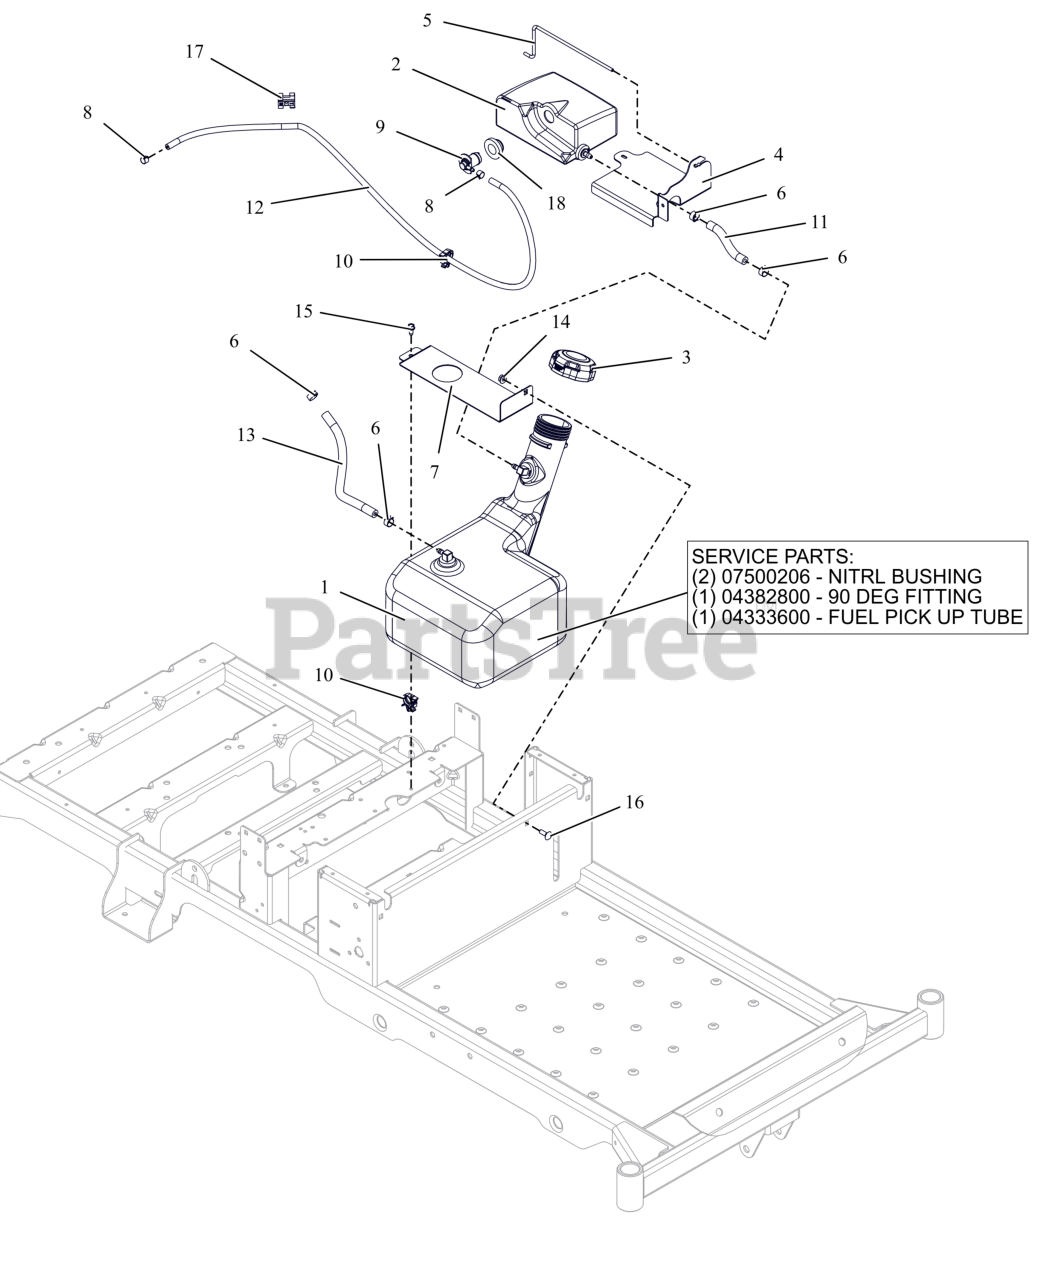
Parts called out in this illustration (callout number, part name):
1	ASM, FUEL TANK-ZOOM
1	BSHG-FLG .375X1.062X.625 NITR
1	FITTING, 90 DEG FUEL-PLASTIC
1	FUEL PICK UP TUBE
2	ASM, FUEL TANK - EXPANSION
3	CAP, FUEL - 2.25 RATCHET INLET VENT
4	BRKT, EXPANSION TANK (ORANGE)
5	ROD, HOLDDOWN (BLACK)
6	CLAMP, FUEL LINE
7	BRKT, TANK STRAP
8	CLAMP-HOSE, SPRING .188
9	VALVE, 2-WAY
10	WIRE CLIP
11	HOSE, .25 LOW-PERM BULK GAS
12	HOSE, .188 LOW-PERM BULK GAS
13	HOSE, .25 LOW-PERM BULK GAS
14	NUT-LK-CTR-FLG .25-20 ZC120
15	SCR-TAP .25-20X.50 HWH ZCC
16	BLT, RHSN .25-20X.750 G5 ZCC
17	CLIP, T, .38-.50
18	GROMMET, REMOTE VENT NITRILE
